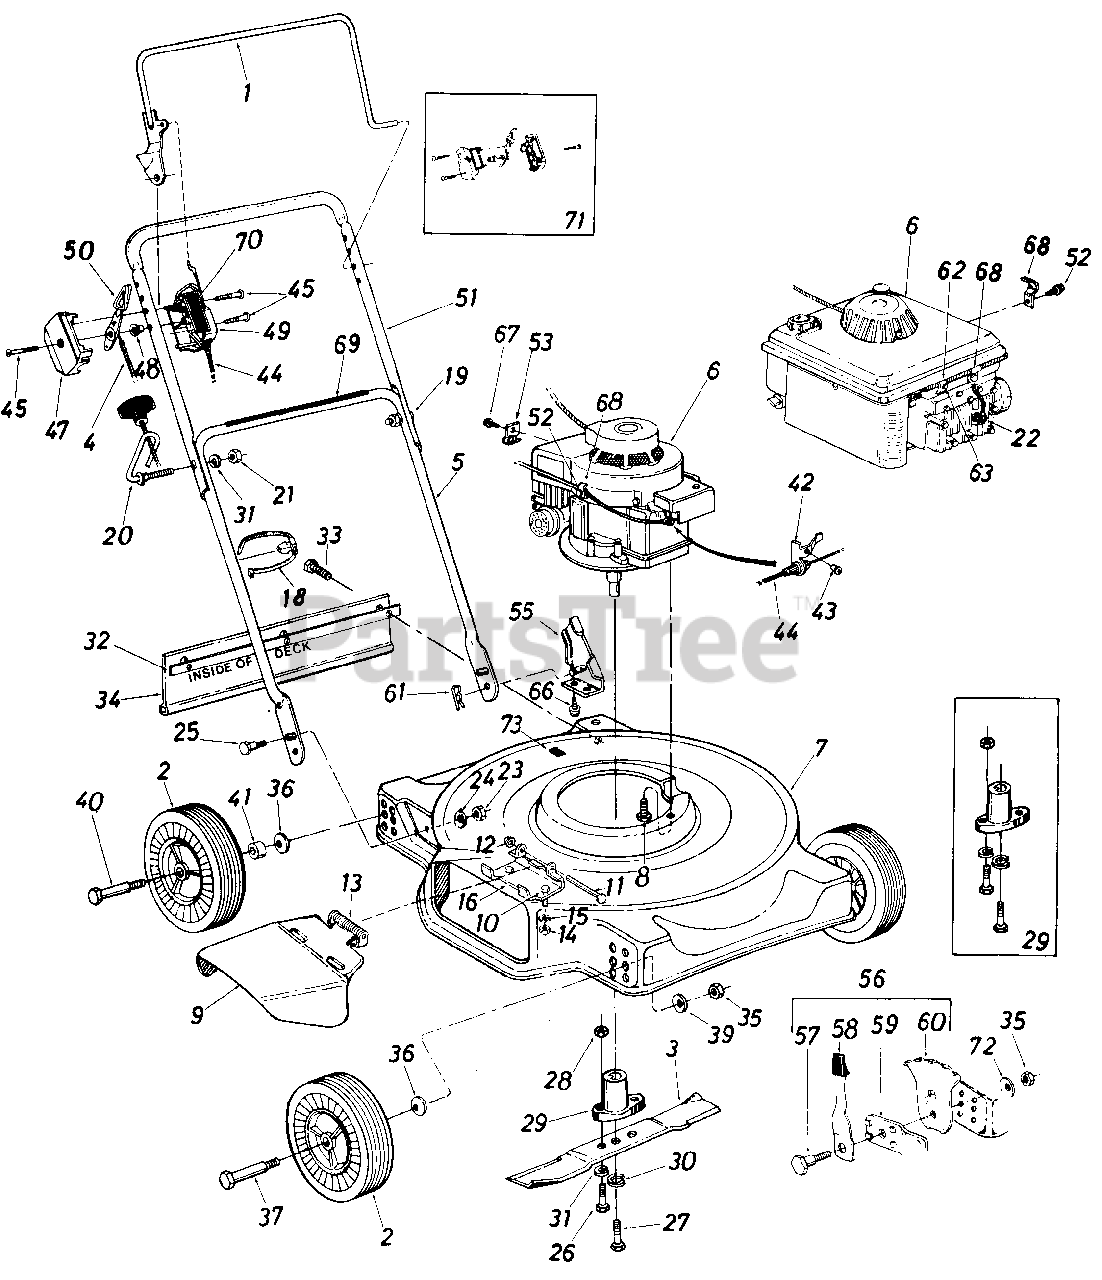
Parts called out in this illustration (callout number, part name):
1	Control Handle Ass'y.-R.H.
2	Wheel Ass'y. Comp.
3	20" Blade
4	Throttle Control Wire-39"
5	Lower Handle (Chrome)
6	Engine
7	20" Deck Ass'y.
8	Hex Wash. Hd. TT-Tap Scr. 3/8-16 x 1.00" Lg.
9	Chute Deflector Ass'y
10	Hex Bolt 1/4-20 x .50" Lg.*
11	Hinge Pin 1/4" Dia. x 3.88 Lg.
12	Push Cap .25" Rod
13	Torsion Spring
14	Hex Nut 1/4-20 Thd.*
15	L-Wash. 1/4" I.D.*
16	Deflector Hinge Plate
18	Cable Tie
19	Curved Carriage Bolt 5/16-18 x 1.38" Lg.
20	Rope Guide Bolt
21	Hex Nut 5/16-18 Thd.*
22	Spark Plug Boot
23	Hex Ins. L-Nut 5/16-18 Thd.
24	Bell-Wash. .345" I.D. x .88" O.D.
25	Shld. Bolt .437" Dia. x .268
26	Hex Bolt 5/16-24 x 1.00" Lg. (Grade 5)
27	Hex Bolt 3/8-24 x 2.25" Lg. (Grade 5)
28	Hex Nut 5/16-24 Thd.*
29	Blade Adapter Kit
30	L-Wash. 3/8" I.D.-H.D.
31	L-Wash. 5/16" I.D.*
32	Retainer Strip
33	Hex Wash. Hd. AB-Tap Scr. 1/4 " x .62" Lg.
34	Rear Flap Ass'y.
35	Hex Nut 3/8-16 Thd.*
36	Bell-Wash. .400" I.D. x .88"
37	Front Axle Bolt
39	Bell-Wash. .39" I.D. x 1.13" O.D.
40	Rear Axle Bolt
41	Spacer .511 I.D. x .70" O.D.
42	Cable Bracket
43	Pop Rivet
44	43" Control Cable-Yellow
45	Truss Mach. Scr. #12 x 1.50"
47	Control Panel Half
48	Control Disc Pin
49	Clutch Panel Half
50	Throttle Control Lever
51	Upper Handle (Chrome)
52	Hex "B" Tap Scr. #10 x .38"
53	Casing Clamp
55	Handle Mount Brkt. Ass'y. L.H.
56	Height Adjuster Ass'y. Comp. R.H.
57	Shoulder Bolt .500" Dia. x .357
58	Spring Lever Ass'y. w/Knob
59	Pivot Bar
60	Index Plate
61	Hairpin Cotter
62	Casing Clamp
63	Hex Self-Tap Scr. #8 x .62"
66	Hex Wash. Hd. Self-Tap Scr. 5/16-18 x .50" Lg.
67	Hex Wash. Hd. AB-Tap Scr. #8 x .38" Lg.
68	Cable Clip
69	Instruction Label-Handle
70	Control Label-Throttle
71	Kit-Control Housing Comp.
72	Belleville Wash. .39 I.D. x 1.4 O.D.
73	Plastic Plug
